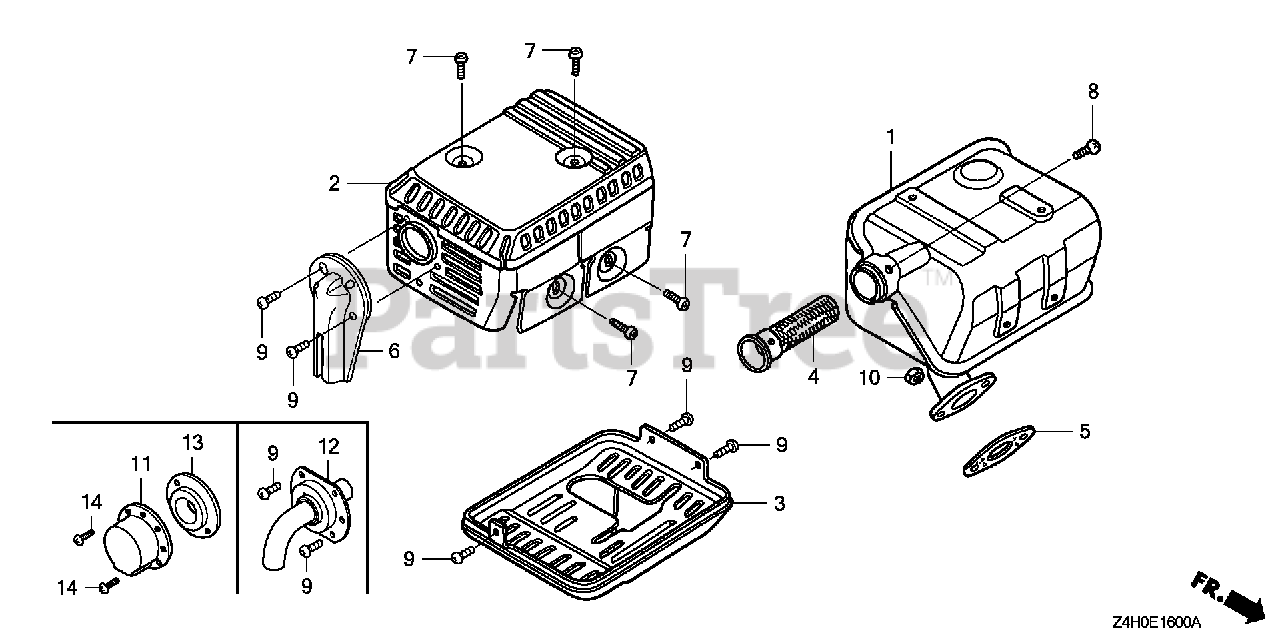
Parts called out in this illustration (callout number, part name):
1	MUFFLER (STD) Use up to Engine SN 1869307.
1	MUFFLER (ARRESTER) (SPARK ARRESTER TYPE)
2	PROTECTOR, MUFFLER (STD) (BLACK)
4	ARRESTER, SPARK
5	GASKET, MUFFLER
7	SCREW, TAPPING (5X8)
8	SCREW, TAPPING (4X6) (TO INSTALL OPTIONAL SPARK ARRESTER)
10	NUT, HEX. (8MM)
